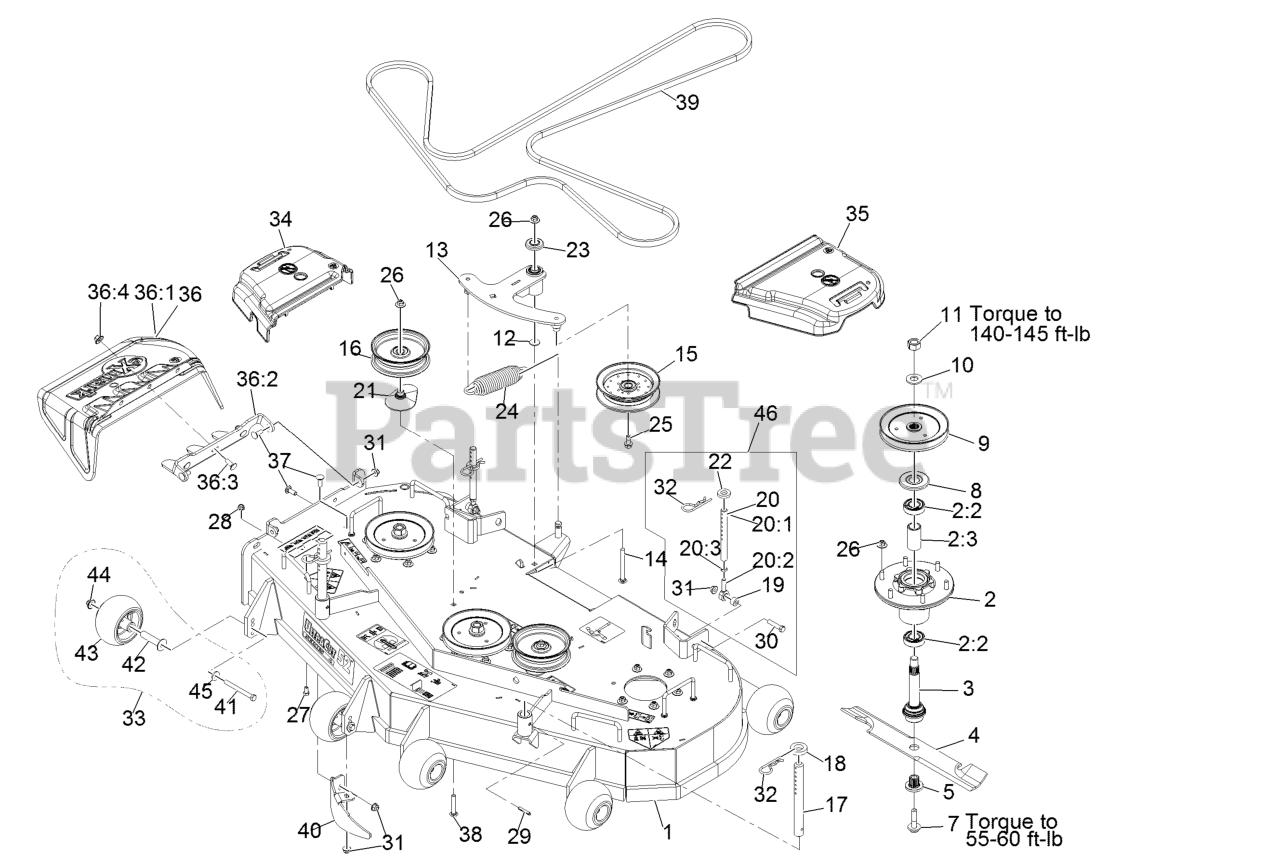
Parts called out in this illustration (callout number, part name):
1	ASM, DECK W/ DECALS, 52"
2	ASM-CUTTER HSG WITH BEARINGS
2:2	BEARING-BALL
2:3	SPACER-BEARING
3	ASM-SPINDLE AND SEAL
5	BUSHING,SPLINED
7	SCREW,SEMS 1/2-20 X 2.19
8	GUARD,BEARING TOP .989
9	SHEAVE,BLADE DRIVE 6.50
11	NUT-HEX
12	WASHER-FLAT
13	ASM, DECK IDLER
14	SCREW-CARR
16	IDLER-PULLEY, FLAT
17	ROD,DECK SUPPORT
18	SPACER-DECK SUPPORT
20:1	LINK,SUPPORT
20:2	BALLJOINT
20:3	NUT-HJ
21	SPACER-PULLEY
23	GUARD-TOP
24	SPRING-EXTENSION
25	SCREW-HFH
26	Nut-Nyloc 3/8-16 Flg
27	SCREW-HH
28	NUT-HF, NI
30	SCREW-HH
31	NUT-HF, NI
32	PIN,HAIR COTTER
33	KIT, ANTI-SCALP ROLLER
34	COVER-BELT, RH
35	COVER-BELT, LH
36	ASM,DISCHARGE CHUTE
36:1	CHUTE,DISCHARGE
36:2	BRACKET,DISCHARGE CHUTE
36:3	SCREW-CARR
36:4	Nut-Nyloc 3/8-16 Flg
37	SCREW-CARR
38	BOLT-CARR, SHORT NECK
39	BELT, DECK DRIVE
40	BAFFLE-DOGLEG, LZ-VT52
41	SCREW-HH 3/8-16 X 3 3/4 GR 8
42	AXLE, ROLLER
43	ROLLER-SCALP, ANTI
44	Nut-Nyloc 3/8-16 Flg
45	WASHER-BELLEVILLE
46	KIT,SUPPORT LINK W/PIN
